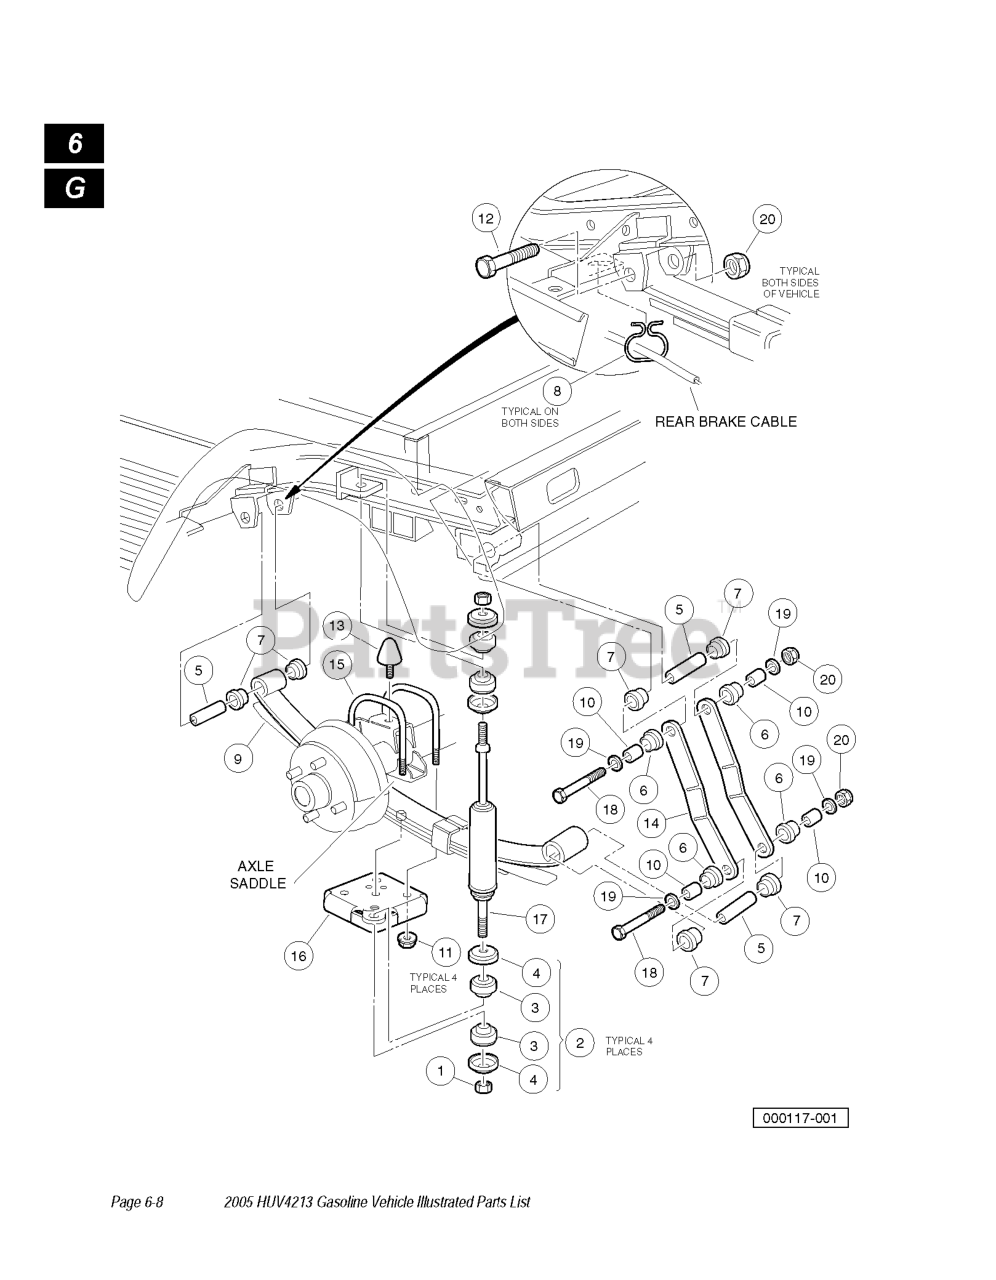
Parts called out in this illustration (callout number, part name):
1	NUT, 3/8-24 HEX
2	SHOCK ABSORBER CUSHION KIT
5	BUSHING - STEEL (GAS CAR)
6	COMPRESSION MOUNT
7	BUSHING, URETHANE
8	HANGER, BRAKE CABLE, LG
9	SPRING, 252 REAR LEAF SPRING
10	SPACER .38 ID X .500 OD
11	LOCKNUT 7/16-14 FLANGE DIMPLE
12	SCREW, 3/8-16 X 3.50 HEX CAP
13	STUD MOUNT
14	SHACKLE, REAR SPRING -GAS 272
16	REINFORCED SPRING PAD
17	SHOCK ABSORBER, REAR
18	BOLT, HEX HEAD
19	WASHER, 3/8 TYPE B FLAT
20	LOCKNUT, 3/8-16 HEX
